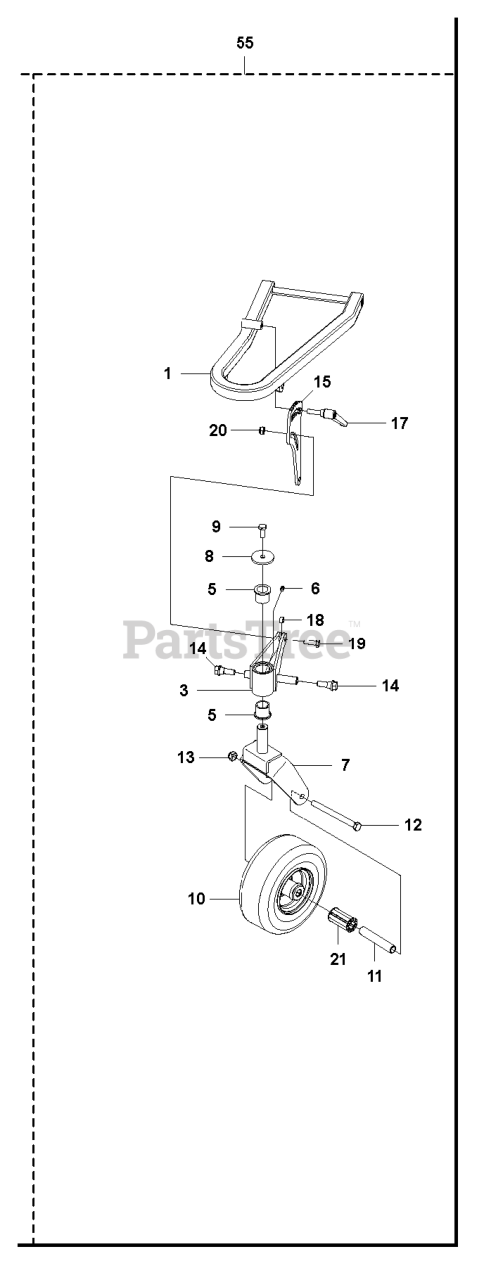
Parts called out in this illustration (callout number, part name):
1	SUPPORTING ARM LEFT
3	PIVOT WHEEL SUPPORT LEFT
5	BEARING BUSHING BRASS
6	GREASE NIPPLE
7	FORK PIVOT WHEEL
10	TIRE/WHEEL.CASTER.9X3.5-4.SMOO
15	SHEET HEIGHT ADJUSTER
17	TURNING KNOB M 10
18	SLEEVE PIVOT WHEEL SUPPORT
20	NUT
21	ROLLER BEARING
55	WHEEL SUSPENSION LEFT
